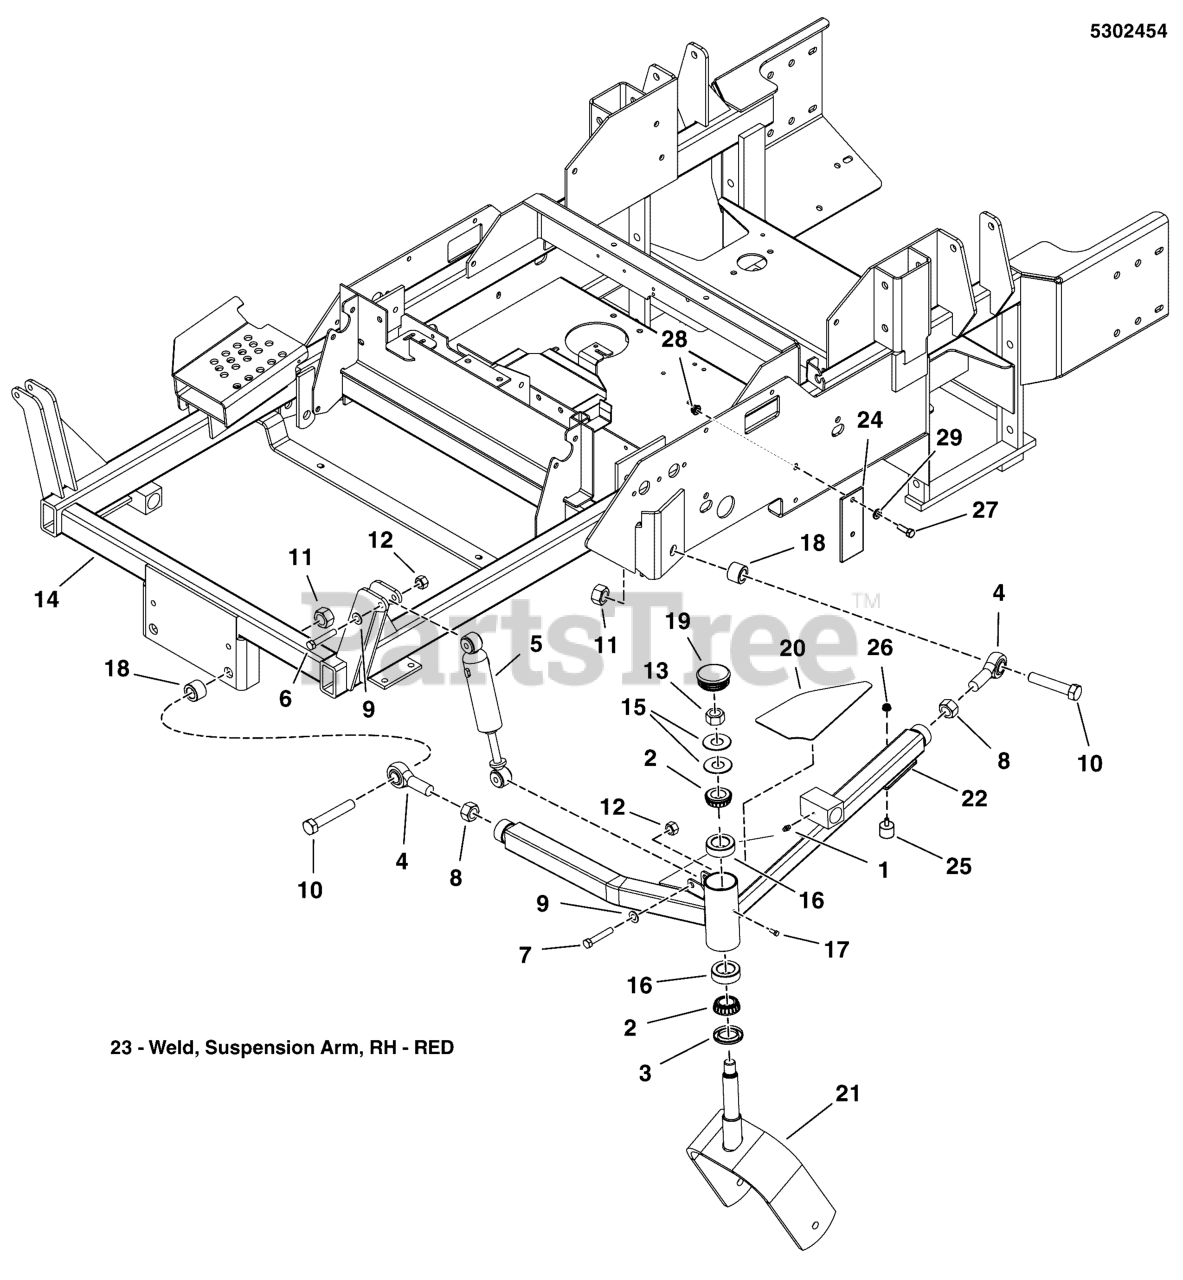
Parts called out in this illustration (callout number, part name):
1	GREASE FITTING, 1/4-28 STRAIGHT
2	BEARING, TAPERED ROLLER, 1
3	SEAL, GREASE
4	BALL JOINT, 3/4-16, MALE
5	COIL-OVER SHOCK ASSEMBLY
6	BOLT, 3/8-16 X 2, GD5, CZ
7	BOLT, 3/8-16 X 2-1/4" GD5 CZ
8	NUT, 3/4-16 HEX JAM
9	WASHER, 3/8 SAE
10	BOLT, 3/4-16 X 3-1/2 YZ GD5
11	NUT, 3/4-16 HEX NYLON LOCK
12	NUT, 3/8-16 HEX NYLOCK FLANGE
13	NUT, 3/4-16, HEX JAM NYLON LOCK
14	* WELD, MAIN FRAME IS5100Z - RED
15	WASHER, BELLEVILLE - 1.500 X .755
16	BEARING CUP
17	BOLT, 1/4-28 X 1/2, GD5 YZ
18	SPACER, .75 X 1.50 X 1.00, CZ
19	CAP, GREASE, LOW PROFILE
20	SAFETY WALK, IS5000 A-ARM STEP
21	WELD, CASTER YOKE -RED
22	WELD, SUSPENSION ARM, LH - RED
23	ARM, Suspension - RH
24	PLATE, REAR DECK STOP
25	BUMPER, RUBBER 1/4-20
26	NUT, 1/4-20 HEX NYLOCK FLANGE
27	BOLT, 5/16-18 X 1 GD5 CZ
28	NUT, 5/16-18 HEX NYLOCK FLANGE
29	WASHER, 5/16" SAE
